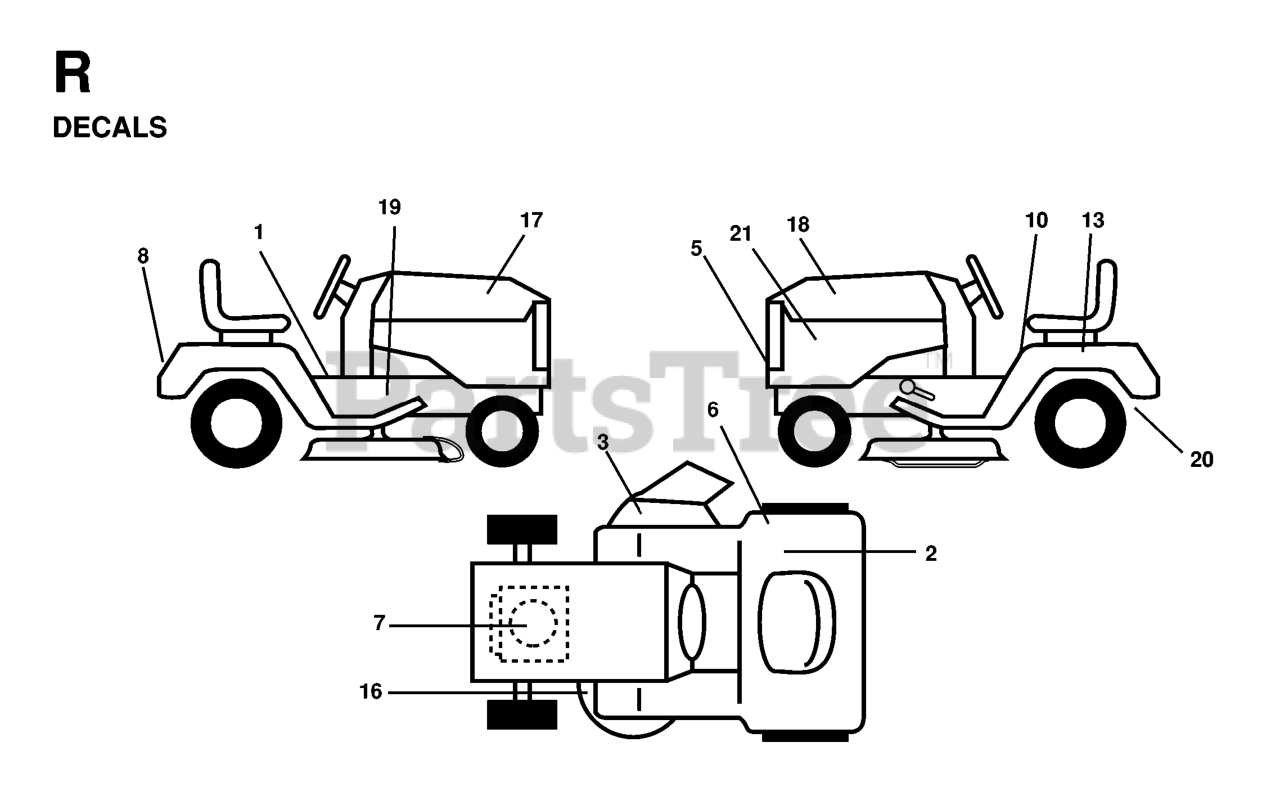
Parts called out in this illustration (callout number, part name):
1	Decal, Brake/Clutch Symbols
2	DECAL
3	DECAL MOWER CUT/FINGER
5	DECAL.GRILLE.HUSQ
6	DECAL EUROPE STANDARD CE
7	DECAL HP ENGINE
8	DECAL FENDER HUSQ
10	DECAL READ OWNER'S MAN SYMS
13	DECAL BTRY SYMBOLS
16	DECAL
19	DECAL
20	DECAL
21	DECAL PNL SIDE
